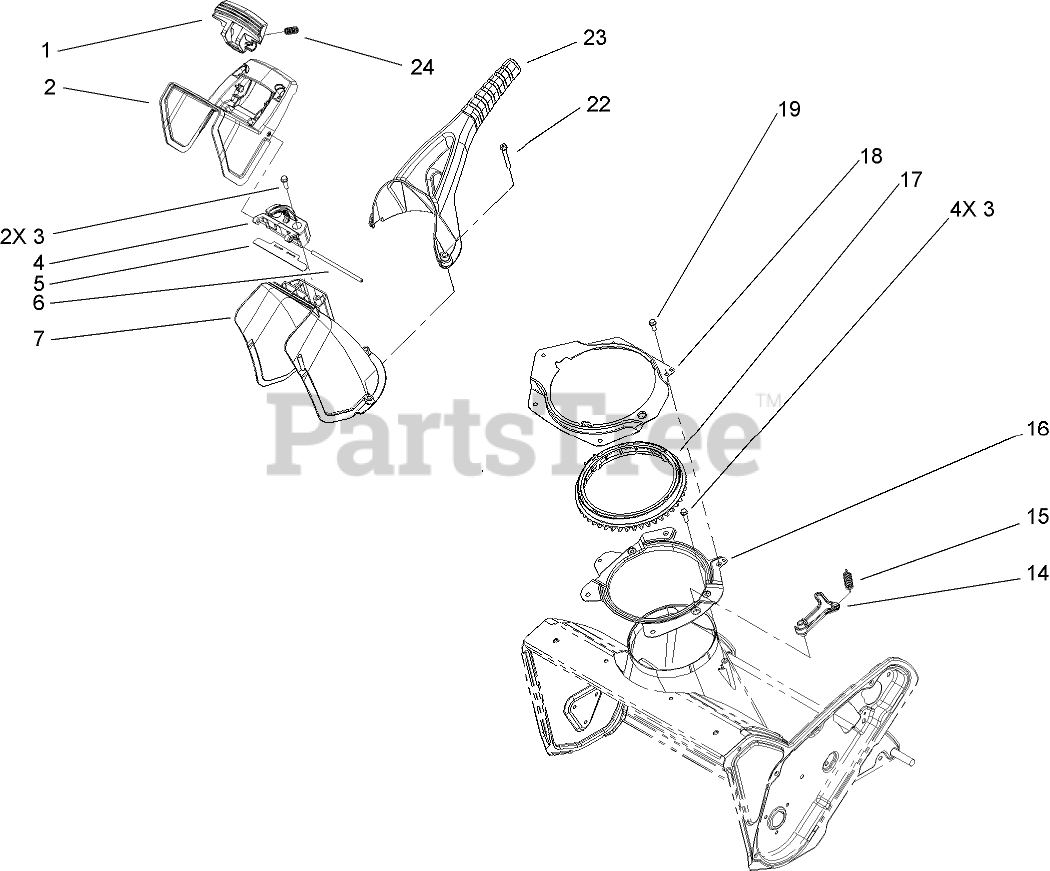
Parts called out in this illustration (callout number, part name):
1	TRIGGER-DEFLECTOR
2	DEFLECTOR-CHUTE, CE
3	SCREW-HWH
4	HINGE-RATCHET, DEFLECTOR
5	SEAL-DEFLECTOR
6	PIN-HINGE, DEFLECTOR
14	PAWL-DETENT
15	SPRING-EXTENSION
16	RING-SUPPORT, CHUTE
17	RING-CHUTE, DETENT
18	RETAINER-RING, CHUTE
19	SCREW-HWH
22	SCREW-HWH, PLASTITE
23	HANDLE-CHUTE
24	SPRING-COMPRESSION
